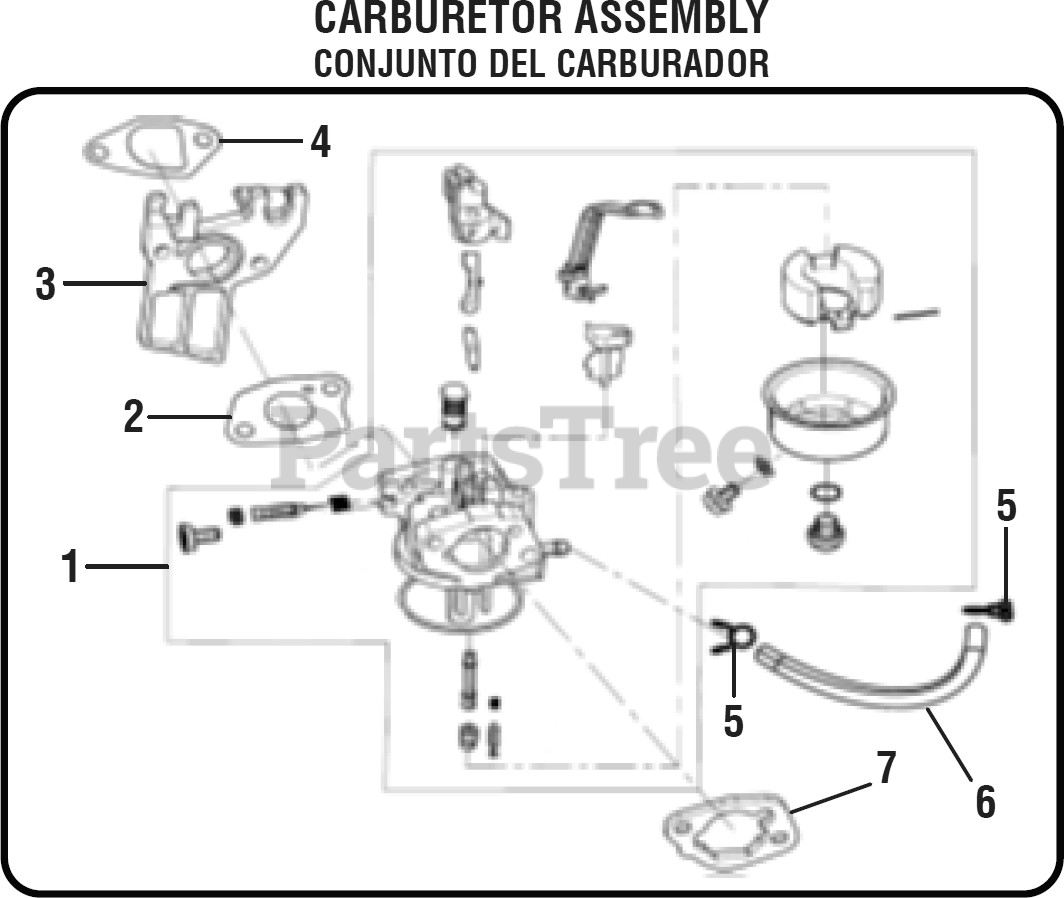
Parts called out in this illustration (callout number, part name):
1	Carburetor Assembly
2	Carburetor Gasket
3	Carburetor Insulator Plate
4	Carburetor Insulator Gasket
7	Air Cleaner Gasket
